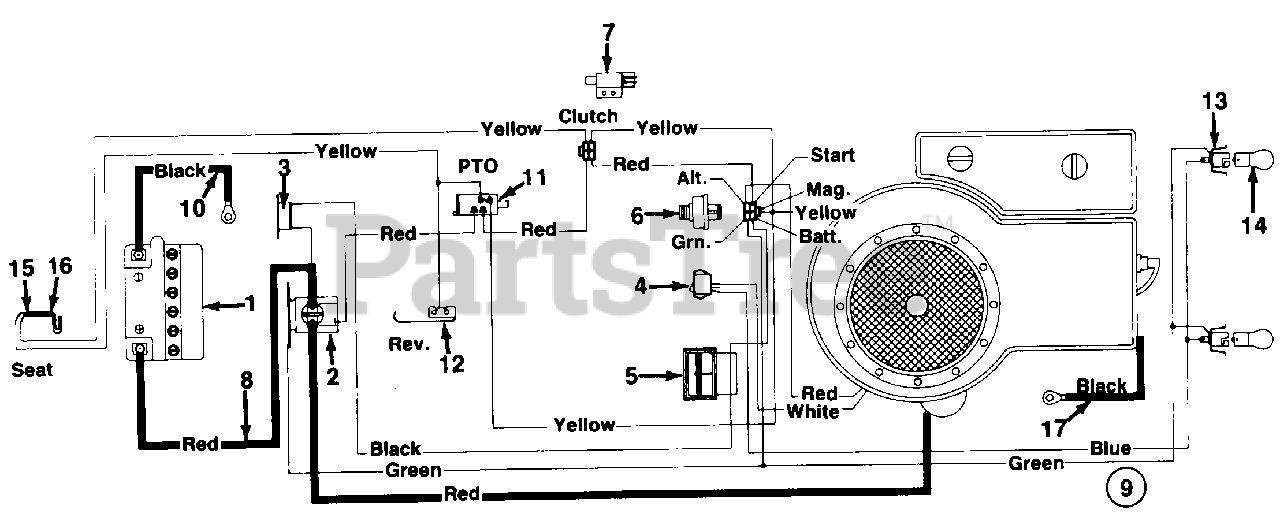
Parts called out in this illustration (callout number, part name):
1	Battery
2	Solenoid
3	Circuit Breaker
4	Light Switch
5	Ammeter
6	Ignition Switch
7	Safety Switch
8	Electric Wire-8" Lg.
9	Wire Harness
10	Ground Wire 11.5 Lg.
11	Safety Switch
12	Safety Switch
13	Socket
14	Bulb
15	Safety-Switch
16	Safety Switch
17	Ground Wire 7.5" Lg.
